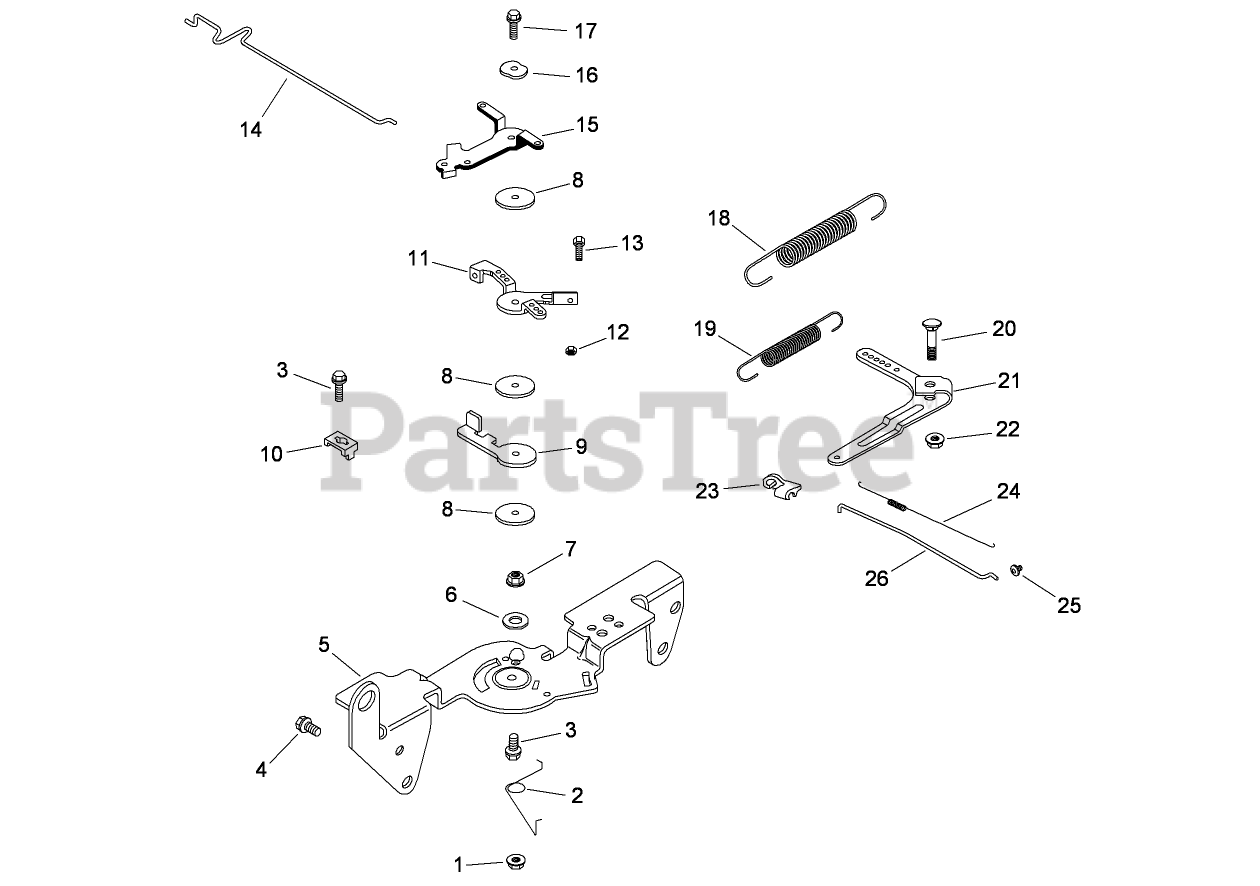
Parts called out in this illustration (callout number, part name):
1	NUT-LOCK (M5X.8)
2	SPRING-RETURN, CHOKE
3	SCREW-FLANGE, THREAD FORMING (M5X0.8X16)
4	SCREW-FLANGE, THREAD FORMING (M6X1.0X16)
5	Bracket-Control
6	Washer-Lock (.25)
7	Nut-HF (M5x0.8)
8	WASHER-FLAT (5.5MM)
9	Lever-Actuator, Throttle
10	CLAMP-CABLE
11	Lever-Control, Throttle
12	NUT (M4X0.7)
13	Screw (M4x0.7x30)
14	Linkage-Choke
15	LEVER-CHOKE
16	WASHER-SPRING (1/4)
17	SCREW-FLANGE, THREAD FORMING (M5X.8X20)
18	Spring-Limiter, Throttle
19	Spring-Governor
20	BOLT-SQ NECK, RD HD (M6X1.0X25)
21	LEVER-GOVERNOR
22	NUT-FLANGE (M6X1.0)
23	BUSHING-RETAINING, LINKAGE
24	SPRING-LINKAGE
25	BUSHING-LINKAGE, THROTTLE
26	Linkage-Throttle
